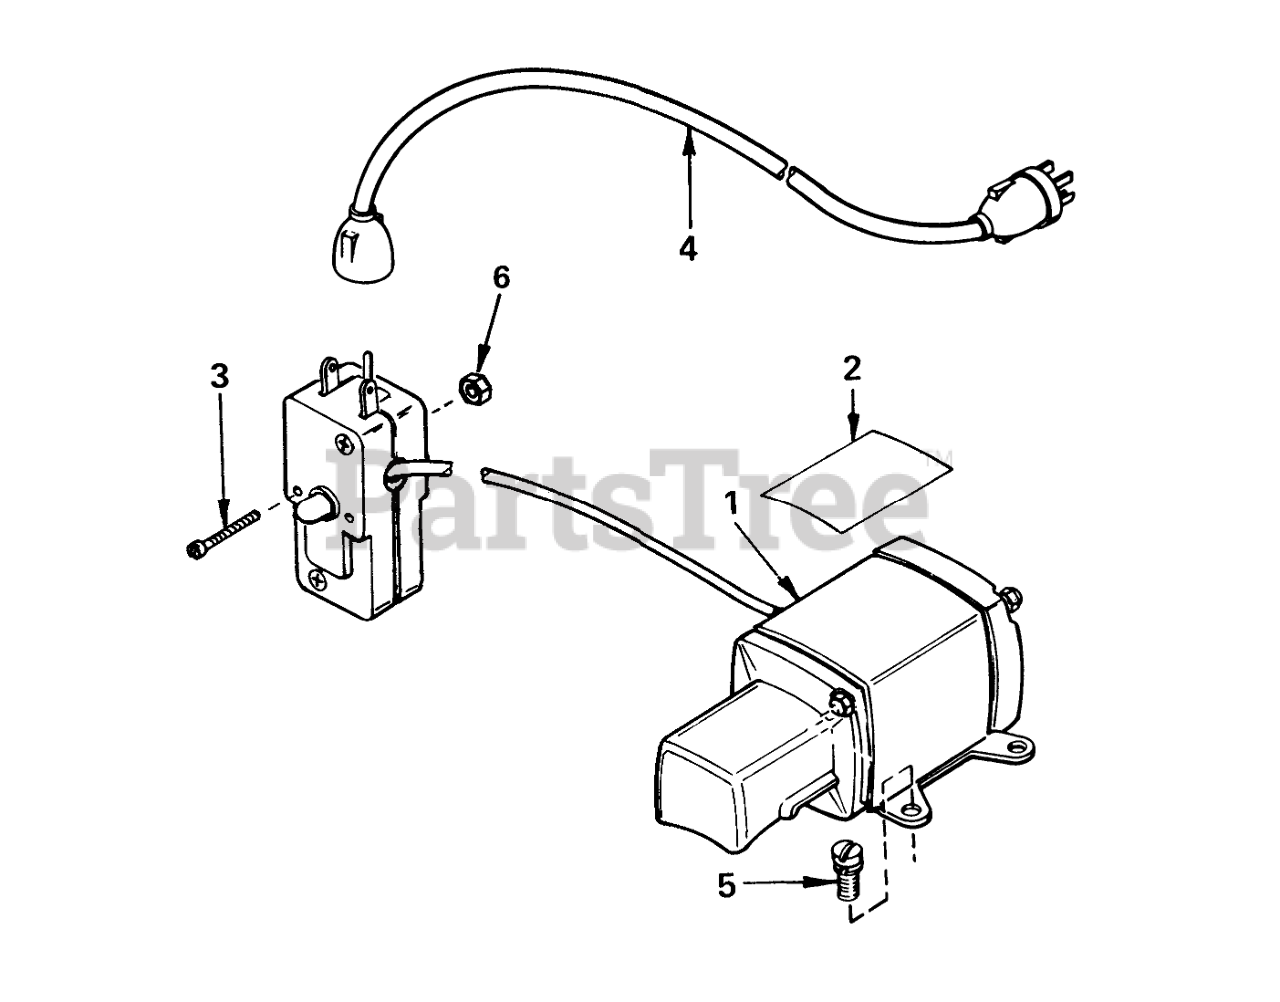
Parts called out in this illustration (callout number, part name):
1	Motor, Cranking (CSA Approved)(Incl. #2 thru 6)
2	Decal
3	Screw, Pan Hd.
4	Cord-Extension
5	Screw (T-30, 1/4-20 x 23/32)
6	Nut & Lockwasher
